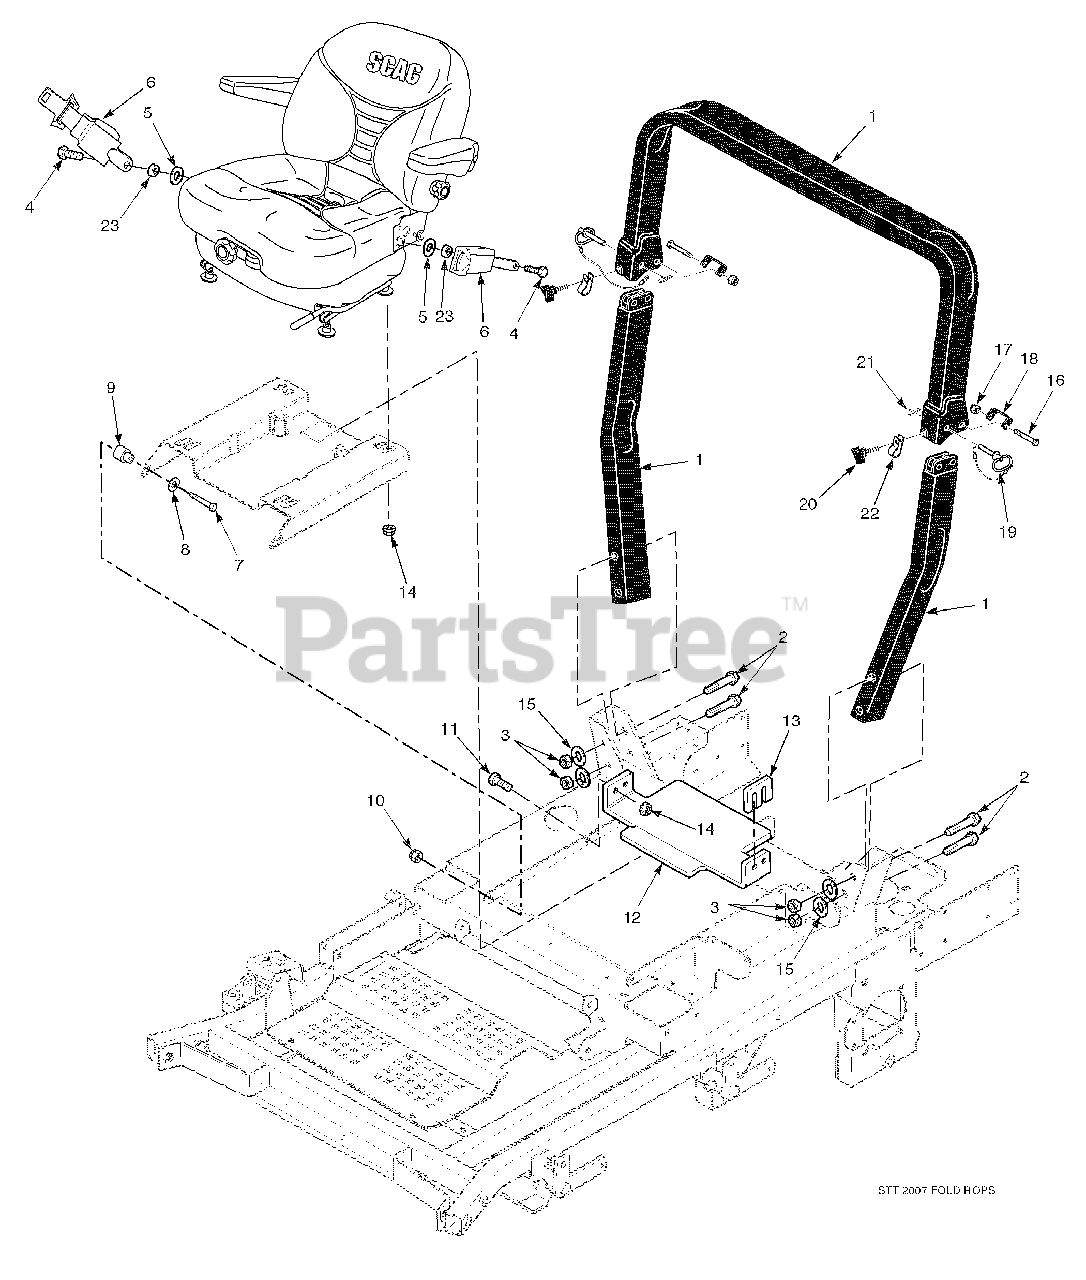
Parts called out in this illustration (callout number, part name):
1	STT, ROPS Accessory
2	Bolt, Hex Head 1/2-13 x 4-1/2”
3	Nut, Center Lock 1/2-13
4	Bolt, Hex Head 7/16-20 x 1”
5	Flatwasher, 7/16-.500 x 1.25 x .083
6	Retractable Seat Belt
7	Bolt, Hex Head 3/8-16 x 2”
8	Flatwasher, 3/8-.391 x .938 x .105
9	Sleeve, Seat Base Mounting
10	Nut, Elastic Stop 3/8-16
11	Bolt, Hex Head 5/16-18 x 1”
12	Bracket, Seat Hold Down with Decal
13	Spacer, Seat Hold Down
14	Nut, Serrated Flange 5/16-18
15	Flatwasher, 1/2-.562 x 1.375 x .109
16	Bolt, Hex Head 1/2-13 x 3-1/2”
17	Nut, Center Lock 1/2-13
18	Bracket, Stop
19	Pin
20	Thumb Screw, 5/16-18 NC x 3-4”
21	Hair Pin, Cotter
22	Clamp
23	Spacer
